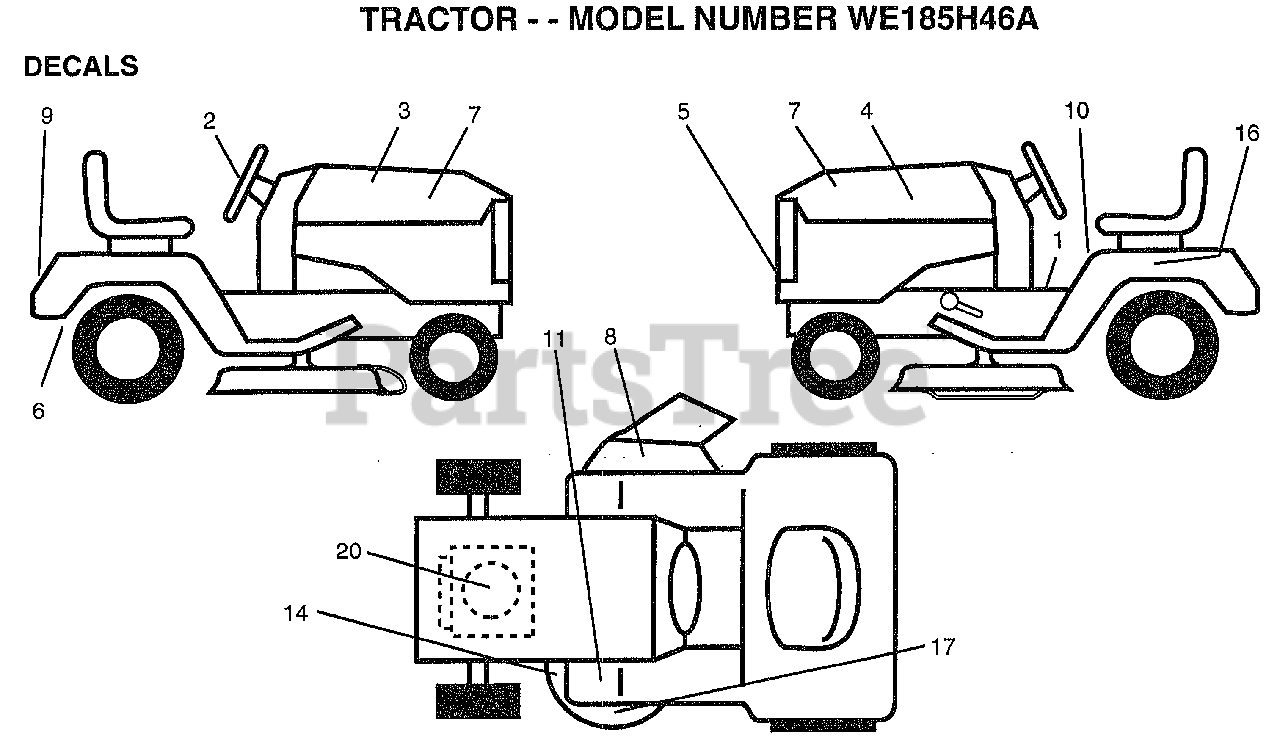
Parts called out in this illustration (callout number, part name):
1	DECAL SADDLE OPER
2	DECAL, INS STRG WH
3	DECAL.HOOD.RH.
4	DECAL.HOOD.LH
5	DECAL, GRILLE LENS
6	DECAL DRAWBAR LH
7	DECAL.PANEL.SIDE
8	"DECAL, WARNING"
9	DECAL.FENDER.LOGO
10	DECAL.CAUT.ENG/FR
11	DECAL T
14	"DECAL.V.BELT.44"""
16	DECAL.BATRY.3-3908
17	DECAL, DECK GRASSEATER
20	DECAL, HP, ENGINE
